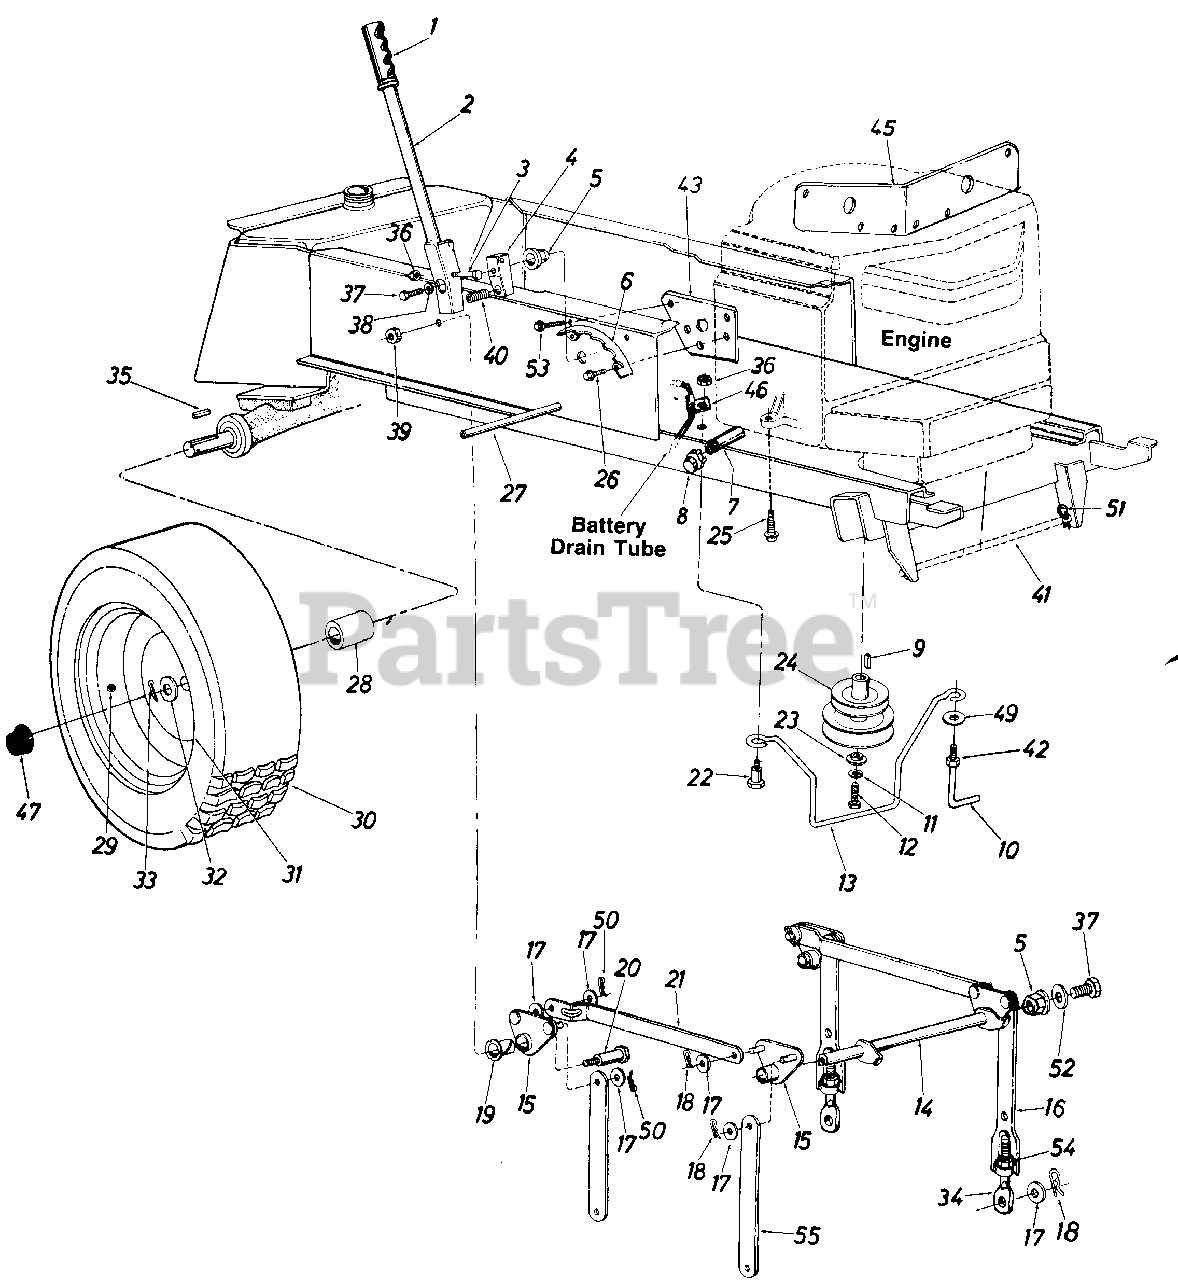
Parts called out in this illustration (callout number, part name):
1	Grip
2	Lift Handle Ass'y.
3	Hex Scr. 5/16-18 x 1.50" Lg.
4	Lift Shaft Drive
5	Plastic Hex Brg. 5/8" I.D.
8	Pipe Cap 3/8-18 Npt.
9	Sq. Key 1/4" x 114" x 1.50" Lg.
10	Belt Guard Lock Pin
11	L-Wash. 7116" Scr.*
12	Hex Scr. 7/16-20 x 1.50" Lg.
13	Belt Guard
14	Lift Shaft Ass'y.
15	Lift Pivot Brkt. Ass'y.
16	Adj. Deck Lift Link
17	Fl-Wash. 112" I.D. x 1.00" O.D. x .090
18	Hairpin Cotter
19	Nyliner 518" I.D. x .88" Lg.
20	Shld. Scr. 518" Dia. x .96" Lg. 3/8-16
23	Flat Wash. .44" I.D. x 1.25" O.D. x .17
24	Two-Step Engine Pulley 4.75" & 5.56
25	Hex Wash. Hd. Scr. 3/8-16 x 1.25" Lg.
26	Hex Thd. Rolling Scr. 5/16-24 x .50" Lg.
27	Running Board Rod
28	Spacer 1.0" I.D. x 1.25" O.D. x 2.12" Lg.
29	Air Valve
30	Rear Wheel Ass'y. Comp.
33	Cotter Pin 3/16" Dia. x 1.50" Lg.
34	Eye Bolt Adj. Link 1/2-13 Thd.
35	Sq. Key 1/4 x 3.0"
36	Hex Cent. L-Nut 5/16-18 Thd.
37	Hex Scr. 5/16-24 x .62" Lg.
38	L-Wash. 5/16" Scr.*
39	Hex Top L-Nut 3/8-16 Thd.
40	Compression Spring
41	Deck Connecting Rod
42	Hex Nut 5/16-24 Thd.*
46	Mounting Clamp
47	Hub Cap
49	Belle-Wash. .39" I.D.
50	Cotter Pin .09 Dia. x 1.0" Lg.
51	Int. Cotter Pin
52	Flat Wash. .34" I.D. x 1.12" O.D. x .125
53	Hex Wash. Hd. AB-Tap Scr. 5/16 x .62" Lg.
54	Hex Nut 1/2-13 Thd.
55	Deck Link
